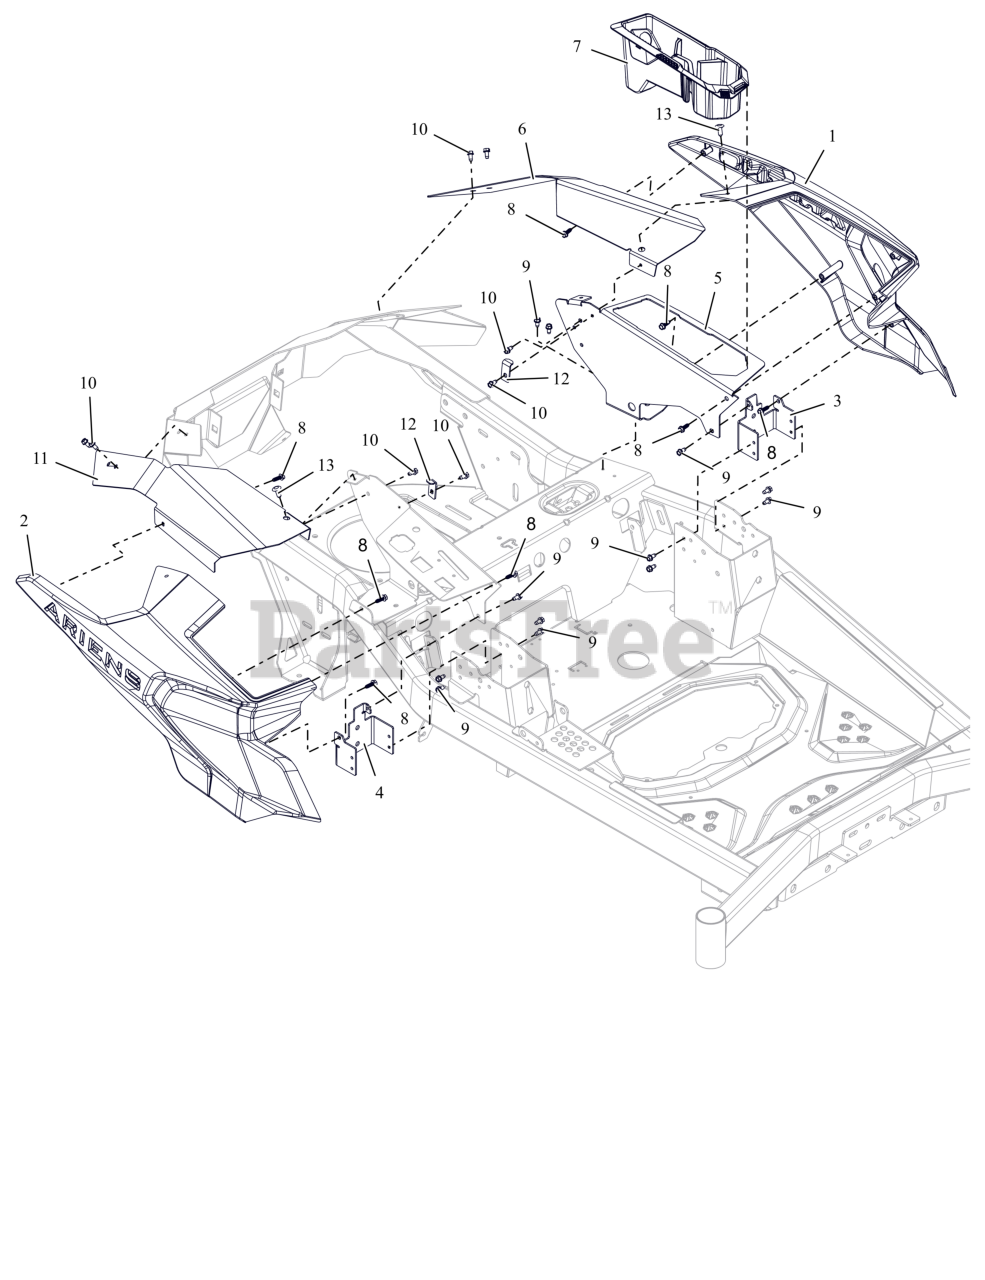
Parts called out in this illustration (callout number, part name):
1	KIT,LH ARIENS FENDER W/ DECAL
2	FENDER-RH-ARIENS
3	BRKT-FRONT FENDER MOUNT-A-RH
4	BRKT-FRONT FENDER MOUNT-A-LH
5	PANEL, CONTROL -LH-ARIENS (BLACK)
6	BRKT, REAR FENDER MOUNT-A-LH (BLACK)
7	HOLDER- CUP - IKON
8	SCR, PLASTITE .25-10X.75 ZCC
9	SCR-TAP .25-20X.50 HWH ZCC
10	SCR-TAP .25X.50 HWH ZB500
11	BRKT, REAR FENDER MOUNT-A-LH (BLACK)
12	PLATE, FENDER HOLDDOWN (BLACK)
13	XMAS TREE FASTNER-BLACK
